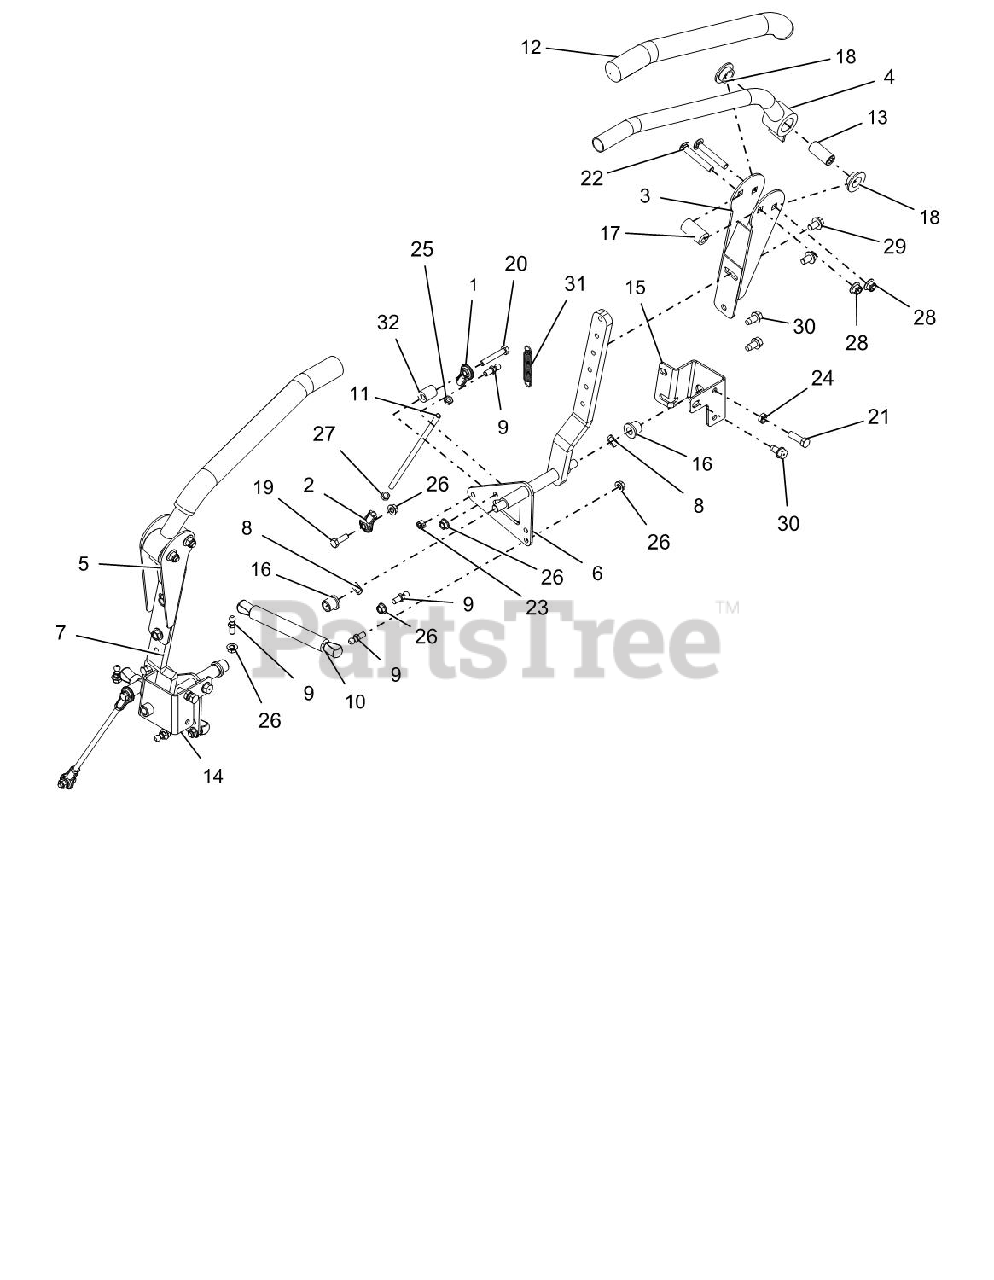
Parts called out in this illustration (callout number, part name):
1	ALIGNABALL, 5/16 RH THREAD
2	ALIGNABALL, 5/16 LH THREAD
3	WLDMT, UPPER ADJUSTABLE CONTROL ARM (BLACK)
4	WLDMT, LH CONTROL HANDLE
5	WLDMT, RH CONTROL HANDLE
6	WLDMT, LOWER LH CONTROL ARM
7	WLDMT, LOWER RH CONTROL ARM
8	WAVE WASHER .531X.781X.125 FH
9	STUD-BALL
10	DAMPER,
11	ROD, STEERING
12	GRIP, HANDLEBAR
13	SPCR, STEERING ARM
14	BRKT, PT200/400 RH CONTROL STOP (RED)
15	BRKT, PT200/400 LH CONTROL STOP (RED)
16	BHSG-FLG .500X.750X.750X.125
17	BSHG, ECCENTRIC .328 X .750 X 1.625
18	BSHG, FLANGE .762 X 1.48 X .44 NYLON
19	BLT-HEX .31-18X1.00 GR5 YWZC
20	BLT-HEX .31-18X2.00 GR5 YWZC
21	BLT-HEX .38-16X1.25 GR5 YWZC
22	BLT-RHDSSQNK .38-16X2.50 G5YZ
23	NUT-LK-CTR .31-18 YWZC
24	NUT, JAM .375-16 YWZC
25	NUT-JAM
26	NUT, LK-TOP-FLG .312-18 YWZC
27	NUT, JAM -LH .31-24 YWZC
28	NUT-LK-NYL-FLG .38-16 YWZC
29	BLT-SERHFWH .38-16X.62 YWZC
30	SCR-TAP .38-16X.75 HWH TR YWZ
31	SPRG, EXTENSION
32	ECCENTRIC
